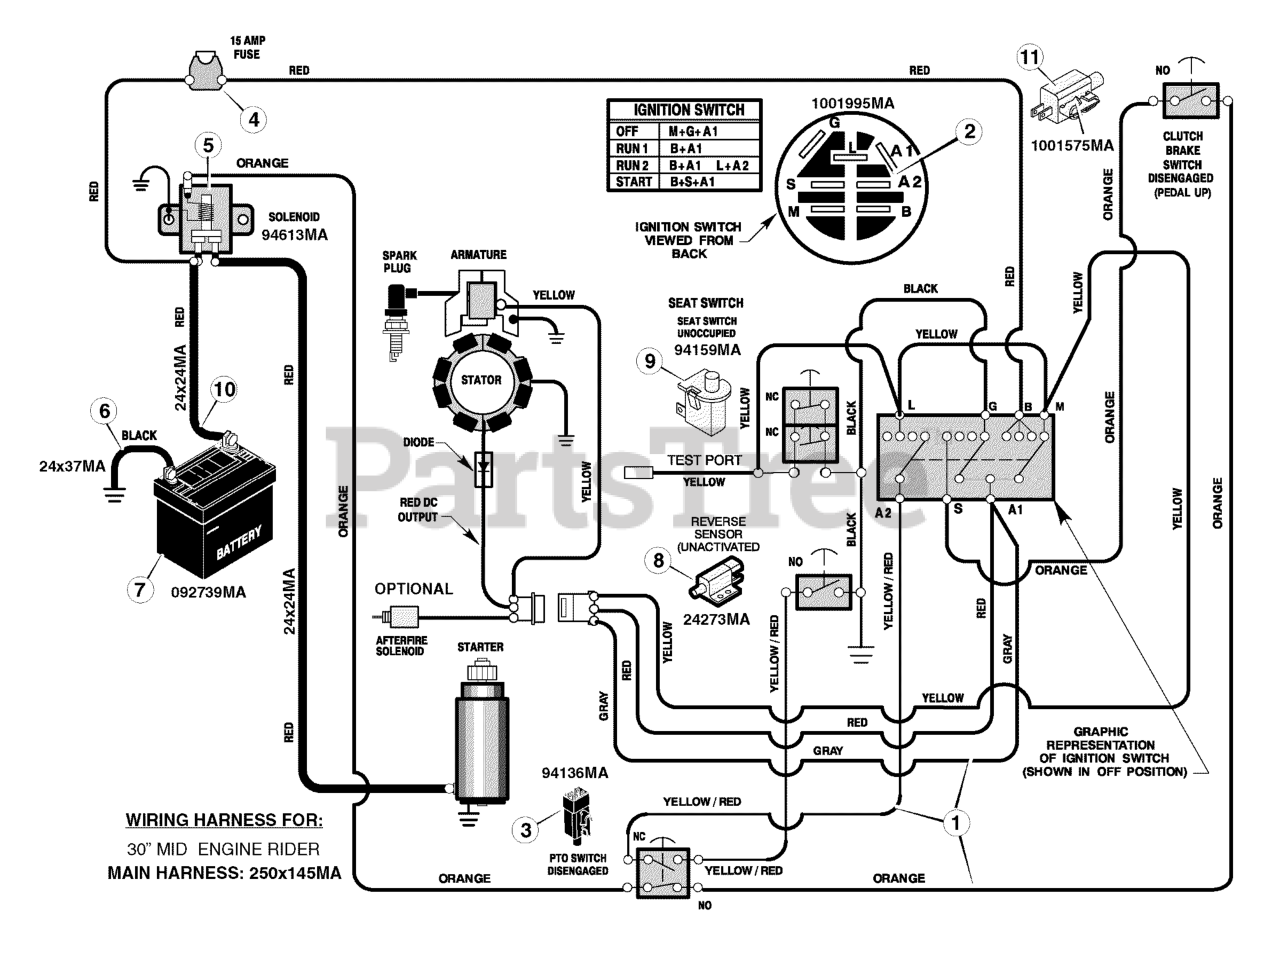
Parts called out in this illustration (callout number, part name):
1	Harness, Chassis Wire
2	Switch, Ignition
3	Switch, Limit
5	Solenoid
6	Cable, Battery Ground
7	Battery
8	Switch, Seat Sensor
9	Cable, Red Battery
11	Switch, Limit
